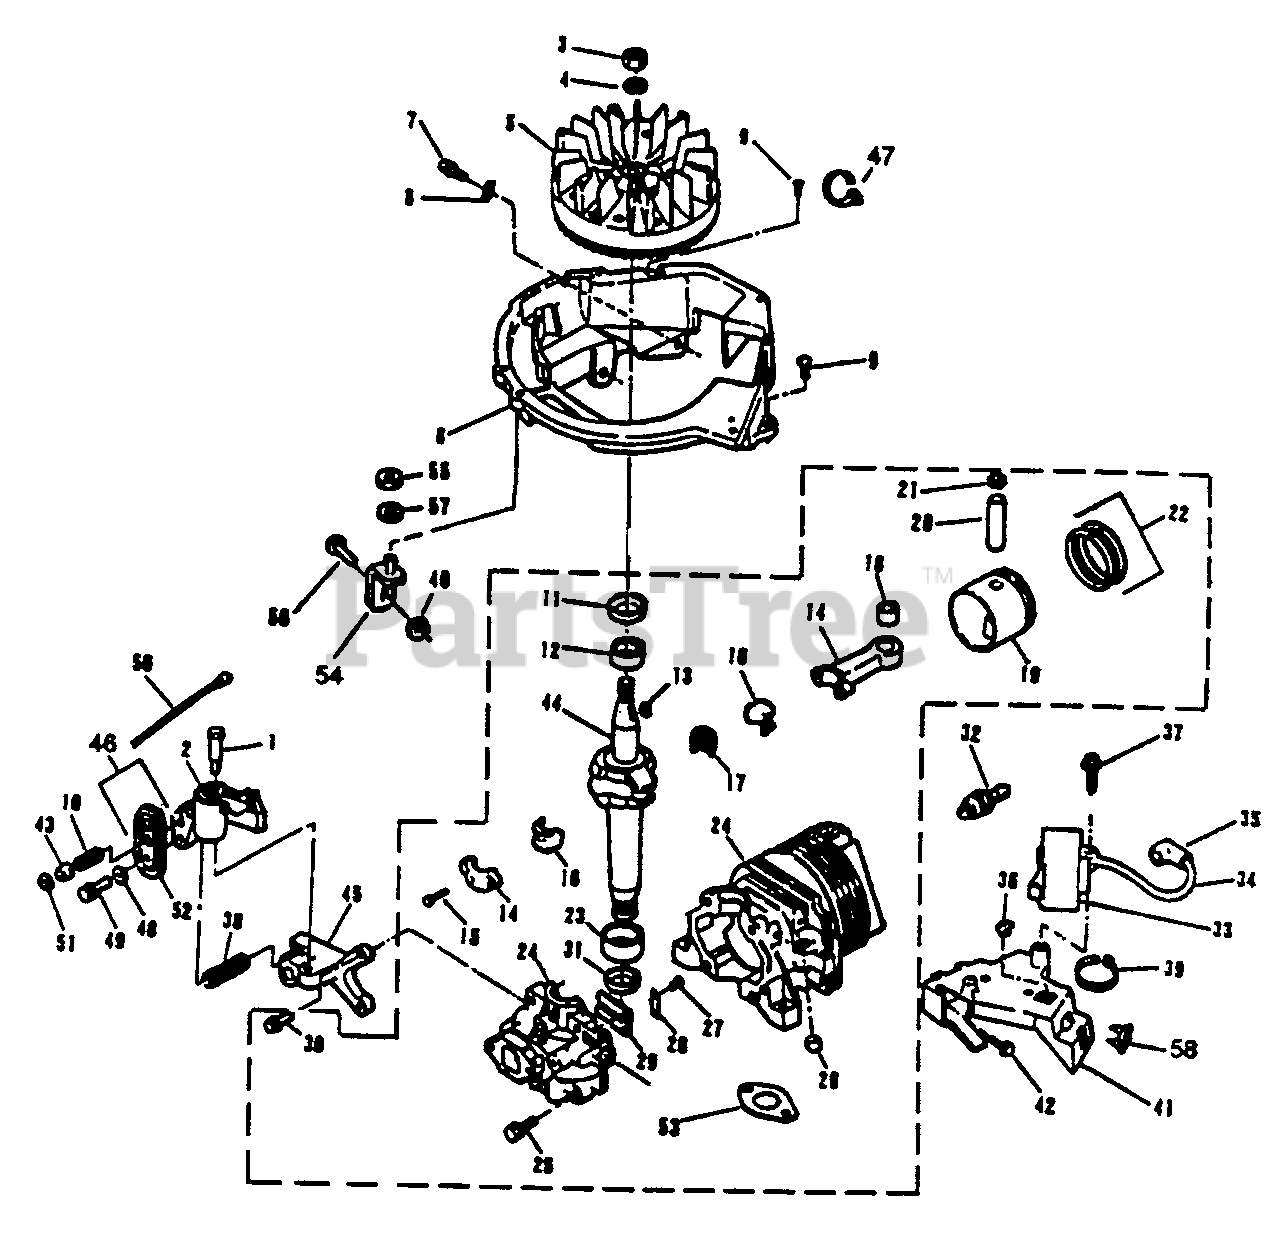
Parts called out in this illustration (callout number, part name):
1	Bolt-Shoulder
2	Brake Assembly
3	Nut-Flywheel
4	Lockwasher
5	Flywheel Assembly
6	Base-Shroud
7	Screw
8	Clip-"J"
9	Screw
10	Spring-Cable Return
11	Oil Seal-Upper
12	Bearing-Main-Upper
13	Key-Flywheel
14	Connecting Rod Assy (Inc. 15-18)
15	Screw-Cap
16	Liner Split
17	Needle Bearing Set
18	Bearing Assembly
19	Piston & Ring Set (Inc. 20-22)
20	Wrist Pin
21	Retaining Ring
22	Ring Set
23	Bearing-Main-lower
24	Cylinder & Crankcase Cover Asy. (Inc. 25-30)
25	Screw-Cover to Crankcase
26	Plug
27	Screw-Reed to C'case Cover
28	Plate-Reed Hold Down
29	Reed
30	Screw-Brake Mounting Bkt.
31	Oil Seal-Lower
32	Spark Plug
33	C.D. Ignition Module & Lead Asy (Inc. 34-35)
34	High Tension Lead & Cvr (Inc. 35)
35	Cover & Terminal Assembly
36	Grommet
37	Screw-C.D. Mounting
38	Spring-Brake
39	Tie Strap
40	Nut
41	Bracket-C.D. Mounting
42	Screw
43	Actuator-Brake Lever
44	Crankshaft
45	Bracket-Brake
46	Switch Assembly (Inc. 47-52)
47	Tie Strap
48	Washer
49	Screw
50	Lead Assembly
51	Retainer
52	Case Assembly-Only
53	Exhaust Gasket
54	Brace Assembly
55	Nut
56	Bolt
57	Washer
58	Speed Nut
